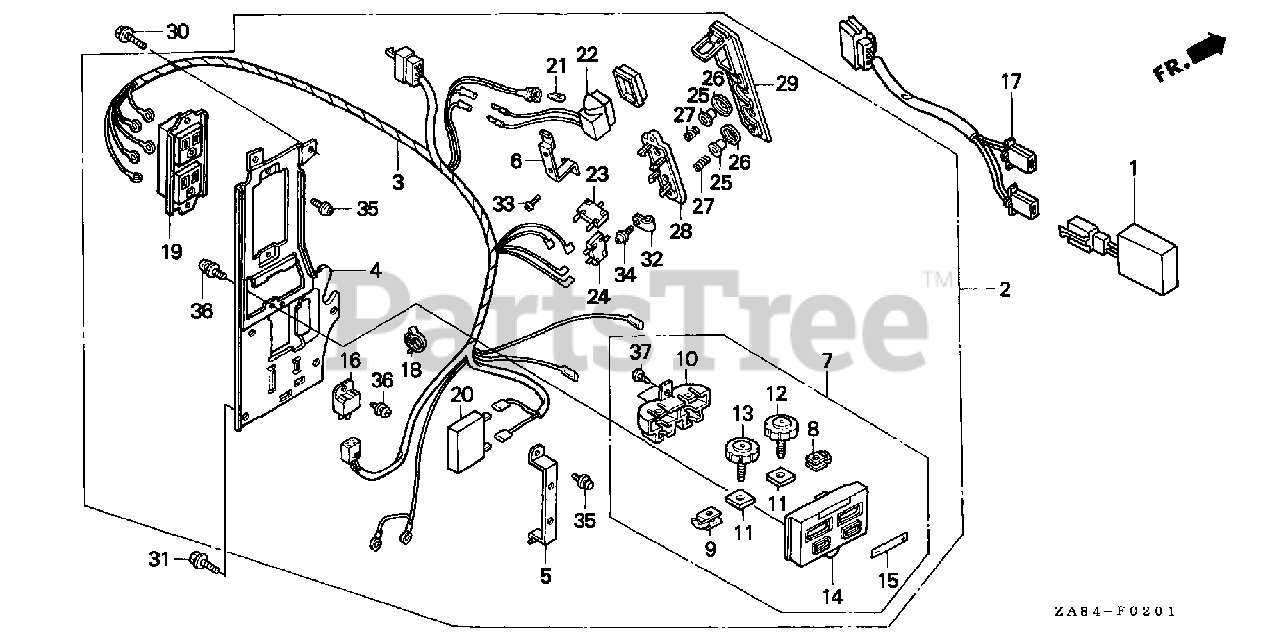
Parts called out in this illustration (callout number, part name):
1	UNIT, IGNITION
2	PANEL ASSY.
3	WIRE HARNESS ASSY.
4	PANEL, CONTROL
5	HOLDER, CONDENSER
6	HOLDER, METER
7	PANEL ASSY., D.C. TERMINAL
8	CONTACT, D.C. TERMINAL (+)
9	CONTACT, D.C. TERMINAL (-)
10	HOLDER, D.C. TERMINAL
12	KNOB, D.C. TERMINAL (+)
13	KNOB, D.C. TERMINAL (-)
14	PANEL, D.C. TERMINAL
15	MARK, D.C. OUT
16	DIODE, D.C.
17	SUB-WIRE HARNESS ASSY.
18	CLIP, HARNESS
19	RECEPTACLE (125V/15A)
20	CONDENSER
21	BULB, WEDGE BASE
22	METER ASSY., FREQUENCY
23	PROTECTOR, CIRCUIT (12A)
24	PROTECTOR, CIRCUIT (5A)
27	SPRING, COIL
28	HOLDER, PROTECTOR
29	PANEL, FR.
30	BOLT, FLANGE (5X12)
31	BOLT, FLANGE (5X10)
32	CLIP (9MM)
33	SCREW, PAN (4X12)
34	SCREW-WASHER (4X14)
35	SCREW-WASHER (4X6)
36	SCREW-WASHER (4X6)
37	SCREW, TAPPING (3X10)
